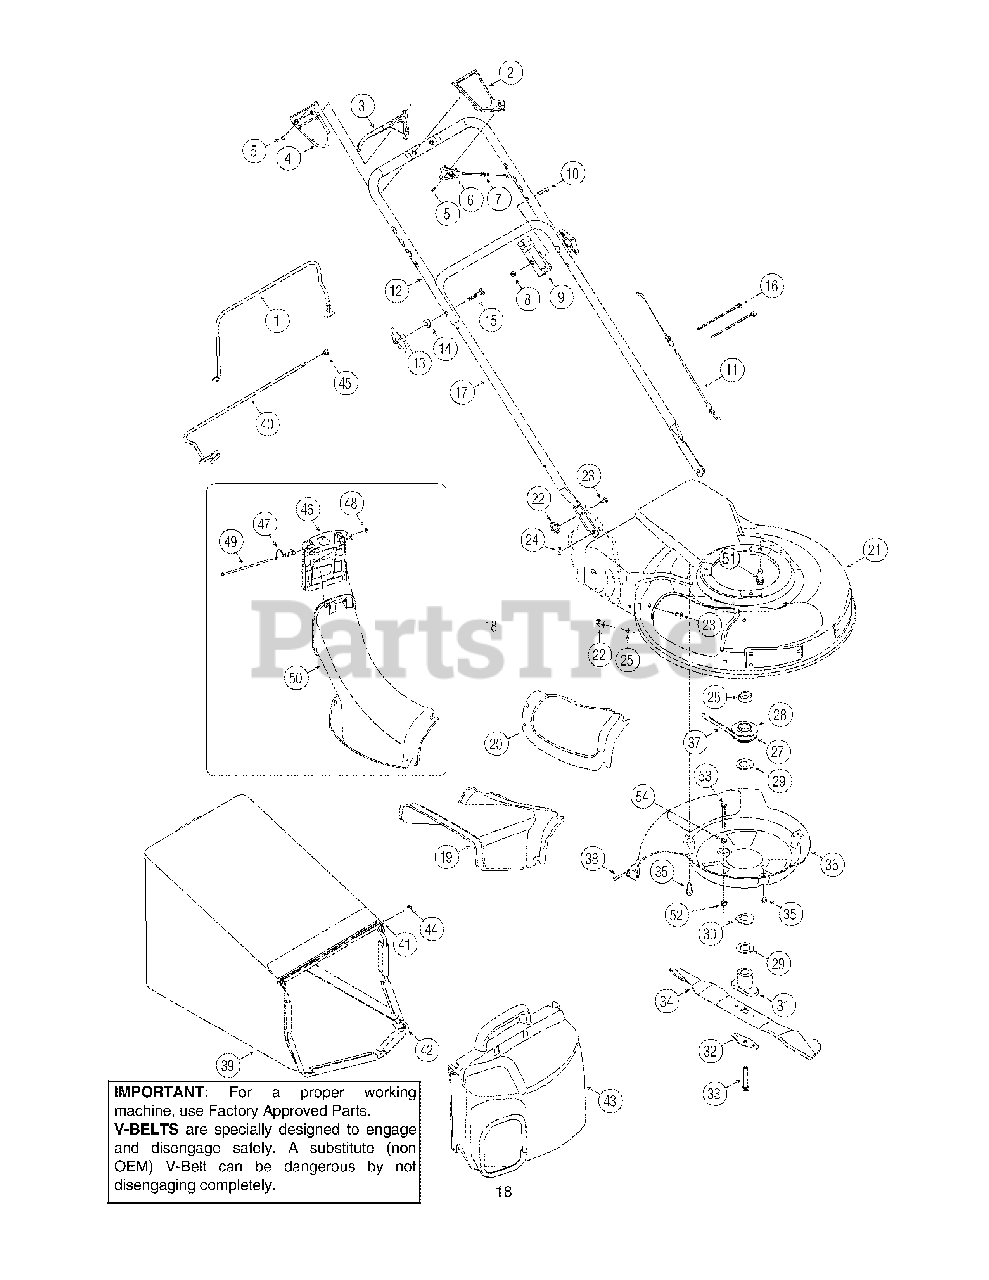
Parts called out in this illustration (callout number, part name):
1	Control Handle
2	Upper Control Housing
3	Control Lever
4	Lower Control Housing
5	C Sunk Tap Screw #10 x.75 Leg
6	Cable Mounting Cap
7	Drive Cable 51"
8	Top Lock Nut 1/4-20
9	Control Housing
10	Oval C-Sunk Screw
11	Control Cable 47"
12	Upper Handle
13	Wing Nut
14	Saddle Washer.320 ID x.830 OD
15	Carriage Bolt 5/16-18 x 2.0
16	Cable Tie
18	Chute Assembly
19	Side-Discharge Chute
20	Mulch Cover
23	Carriage Bolt 1/4-20 x .75"
24	Cotter Pin
25	Push Nut .25 x ID x .50 OD
26	Sleeve Spacer 25mm x 1.375 x .440
27	Half Pulley: Key 25mm x 2.62 OD
28	Half Pulley: Upper 25mm x 2.62
29	Flat Washer 1.00 x 1.75 x .107
30	Spring Washer 1.005 x 1.825 x .048
31	Blade Adapter Kit
32	Blade Bell Support
33	Hex Bolt 3/8-24 x 2.5
34	21" Mulching Blade
35	Screw 1/4-20 x 0.375"
37	Belt 3/8 x 39.24
38	HL Screw #12-16 x 1.00
39	Grass bag
40	Support Rod w/ Rope Guide
41	Pivot Rod
42	Grass bag Frame
43	Grass bag Cover
44	Cap Nut
45	Hex Nut 5/16-18
46	Chute Door
47	Torsion Spring
48	Push Cap
49	Pivot Rod
50	Discharge Chute
51	Sems Screw 3/8-16 x 1.00
52	Flange Lock Nut, 14-20
53	Special Screw
54	Hex Nut, 1/4-20
